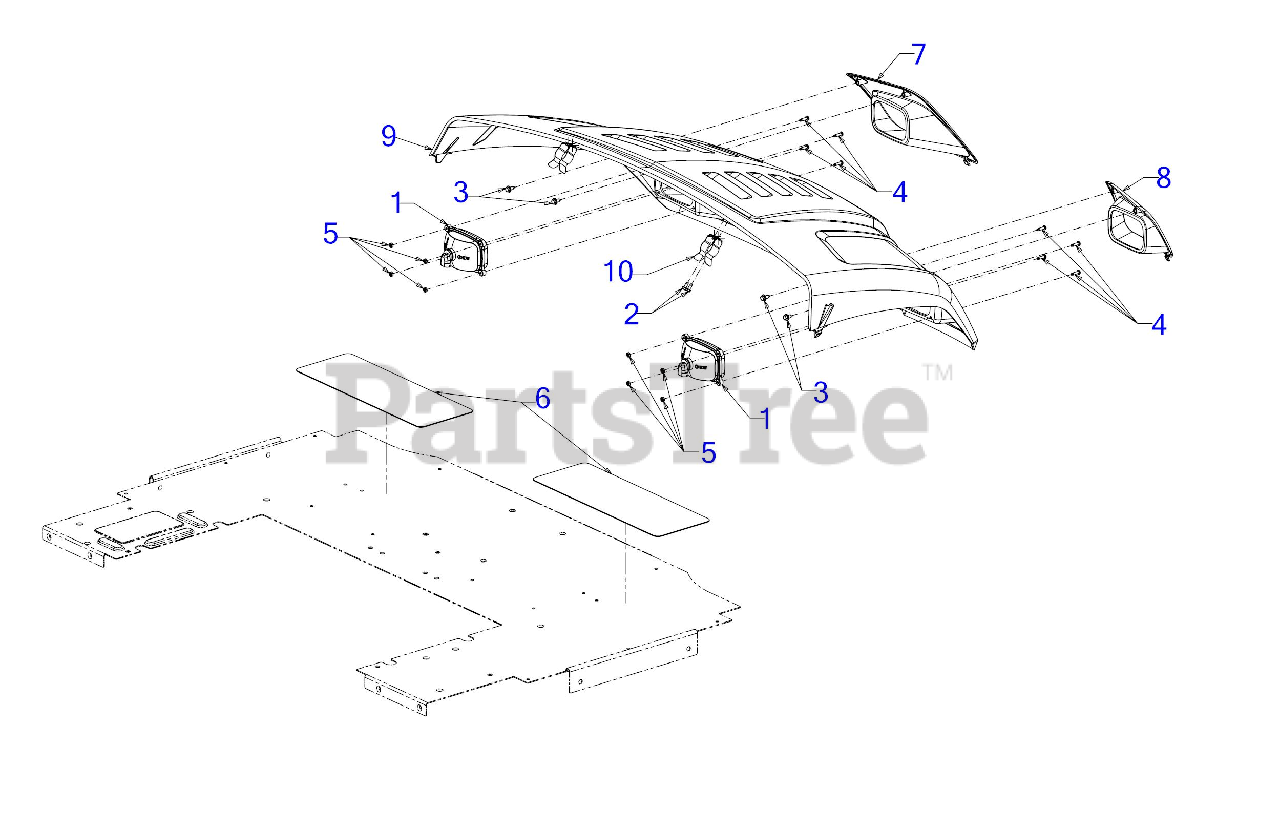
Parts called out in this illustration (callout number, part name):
1	HEADLIGHT ASSEMBLY
2	HEX SCREW #12-16 x .50
3	SCREW 1/4-20X.625
4	SCREW #10-24 x .750
5	LOCK NUT 10-24
6	FOOT REST PAD
7	HEADLIGHT BEZEL (LH)
8	HEADLIGHT BEZEL (RH)
10	HOOD LATCH SPRING
